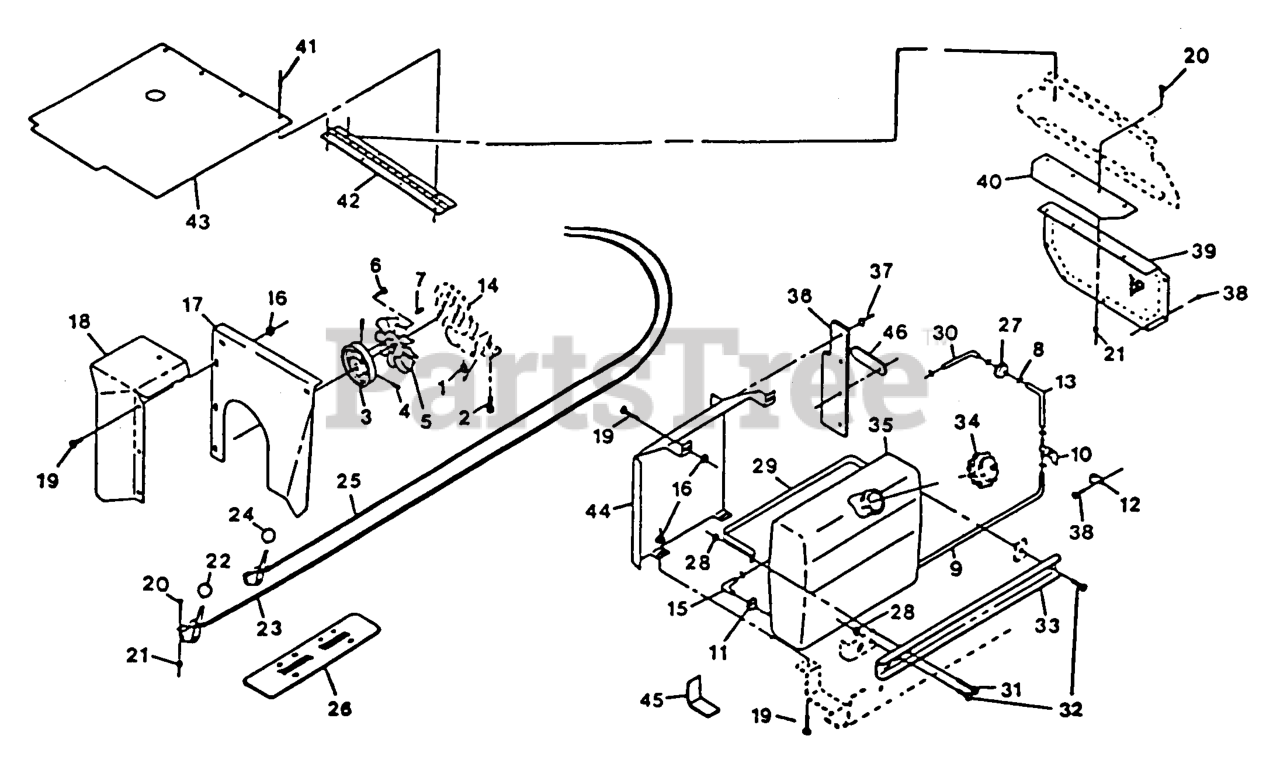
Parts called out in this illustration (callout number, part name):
4	SCREW-SET
9	FUEL LINE,19.0
10	VALVE-FUEL
12	CLIP-LOOM
14	Engine, Kohler Ch 20s
15	ELBOW-TANK, FUEL
17	SHIELD,HEAT FRONT
22	KNOB-BALL
23	CABLE,THROTTLE
24	KNOB-BALL, BLACK
25	CABLE,CHOKE
29	STRAP,FUEL TANK 3.8GAL
30	HOSE-FUEL
31	Bolt, Tap 1/4-20 X 2-1/2
34	CAP-FUEL
36	BAFFLE,ENGINE LH
37	RIVET-POP
41	Rivet, 3/16 X 1/4
42	HINGE,ENGINE COVER
44	SHIELD,HEAT FUEL TANK
45	PAD,FUEL TANK
46	CLIP-BAFFLE, REAR
